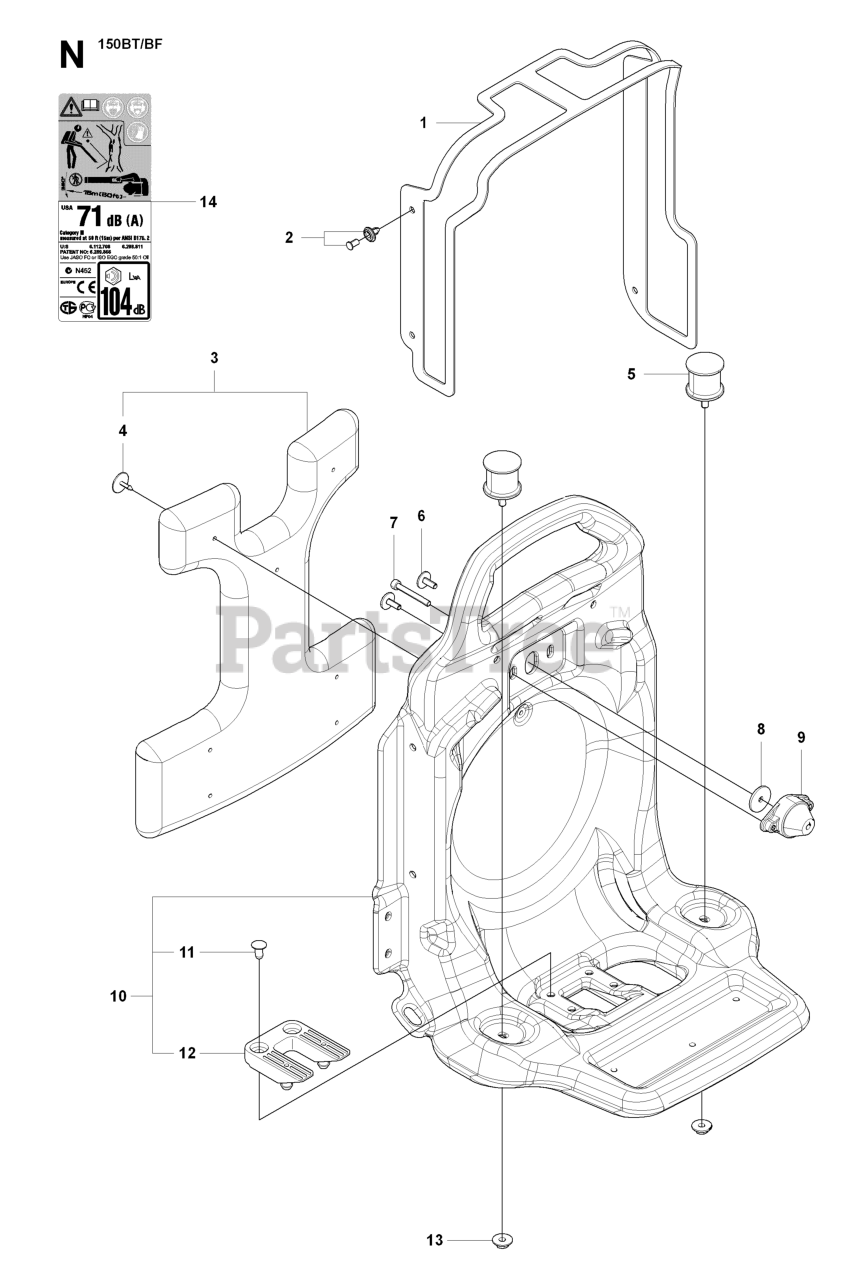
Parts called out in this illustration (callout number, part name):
2	CLIP
3	PAD COMP
4	CLIP
5	DAMPER
7	BOLT
8	WASHER
9	DAMPER
11	CLIP
13	NUT (M6)
